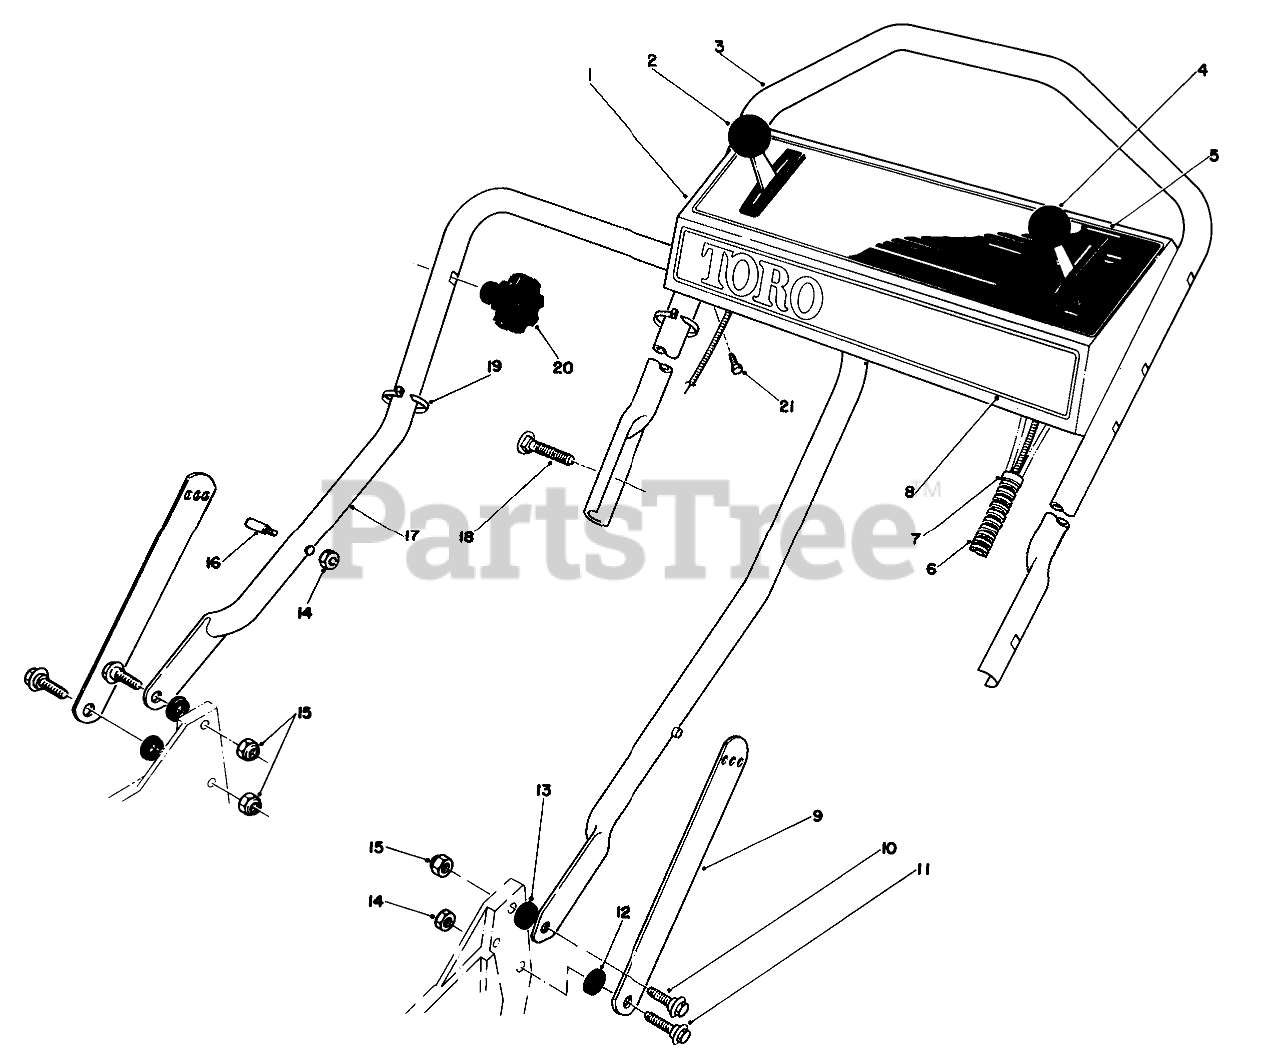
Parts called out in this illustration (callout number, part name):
1	Panel-Control (Incl. Ref. #5)(used on units with Serial No. 6000101-6002200)
1	Panel-Control
2	SERVICE THROTTLE CONTRO
3	Handle-Upper
4	THROTTLE CONT-SERVICE
5	Decal-Instruction Panel
6	CONTROL CABLE COVER
7	FITTING-RING
8	Decal-Toro
9	Handle Latch
10	SCREW-SHOULDER
11	SCREW-SHOULDER
12	SPACER
13	SPACER
14	NUT-LOCK, NI
15	NUT-LOCK, NI
16	HANDLE PIN
17	Handle-Lower
17	LOWER HANDLE ASM
18	5/16-18 X 2 HNDLE SCREW
19	TIE-CABLE
21	SCREW-HWHTF
